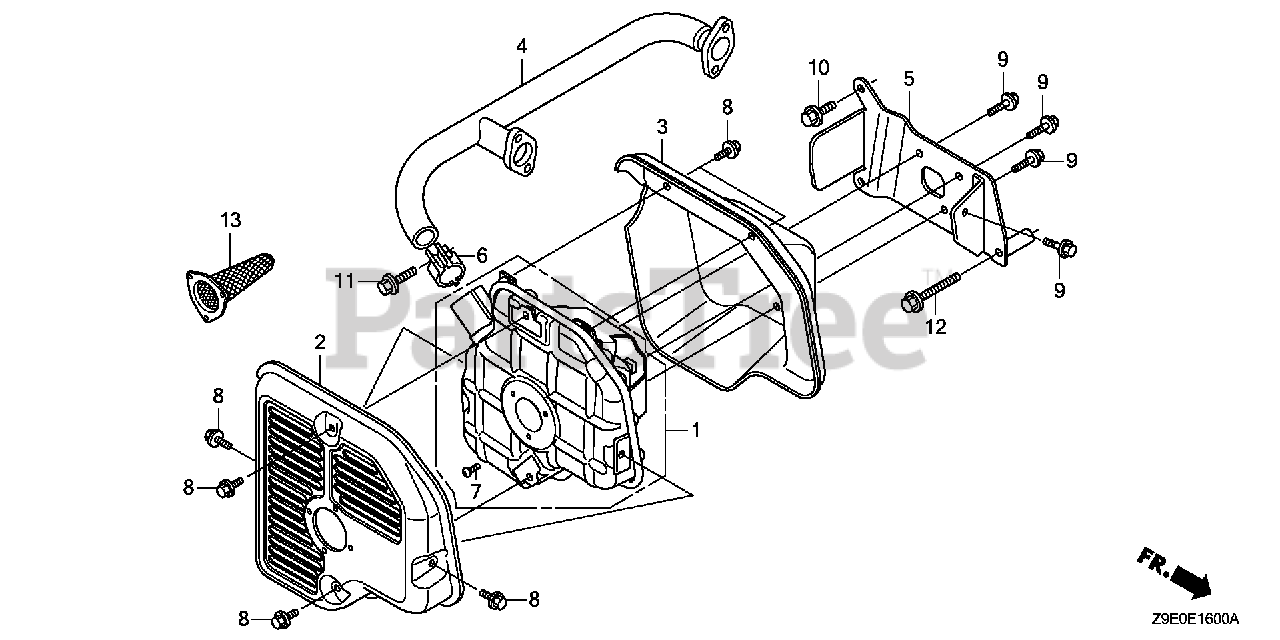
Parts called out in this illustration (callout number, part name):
2	PROTECTOR, MUFFLER (OUTSIDE) (NOT AVAILABLE)
2	PROTECTOR, MUFFLER (OUTSIDE)
3	PROTECTOR, MUFFLER (INSIDE) (NOT AVAILABLE)
3	PROTECTOR, MUFFLER (INSIDE)
5	STAY, MUFFLER
6	BAND, MUFFLER
7	SCREW, PAN (4X8)
8	BOLT, FLANGE (6X8)
9	BOLT, FLANGE (6X12) Use up to Engine SN 1543277.
10	BOLT, FLANGE (8X20) Use up to Engine SN 1609606.
11	BOLT, FLANGE (8X30)
12	BOLT, FLANGE (8X60)
13	ARRESTER, SPARK
